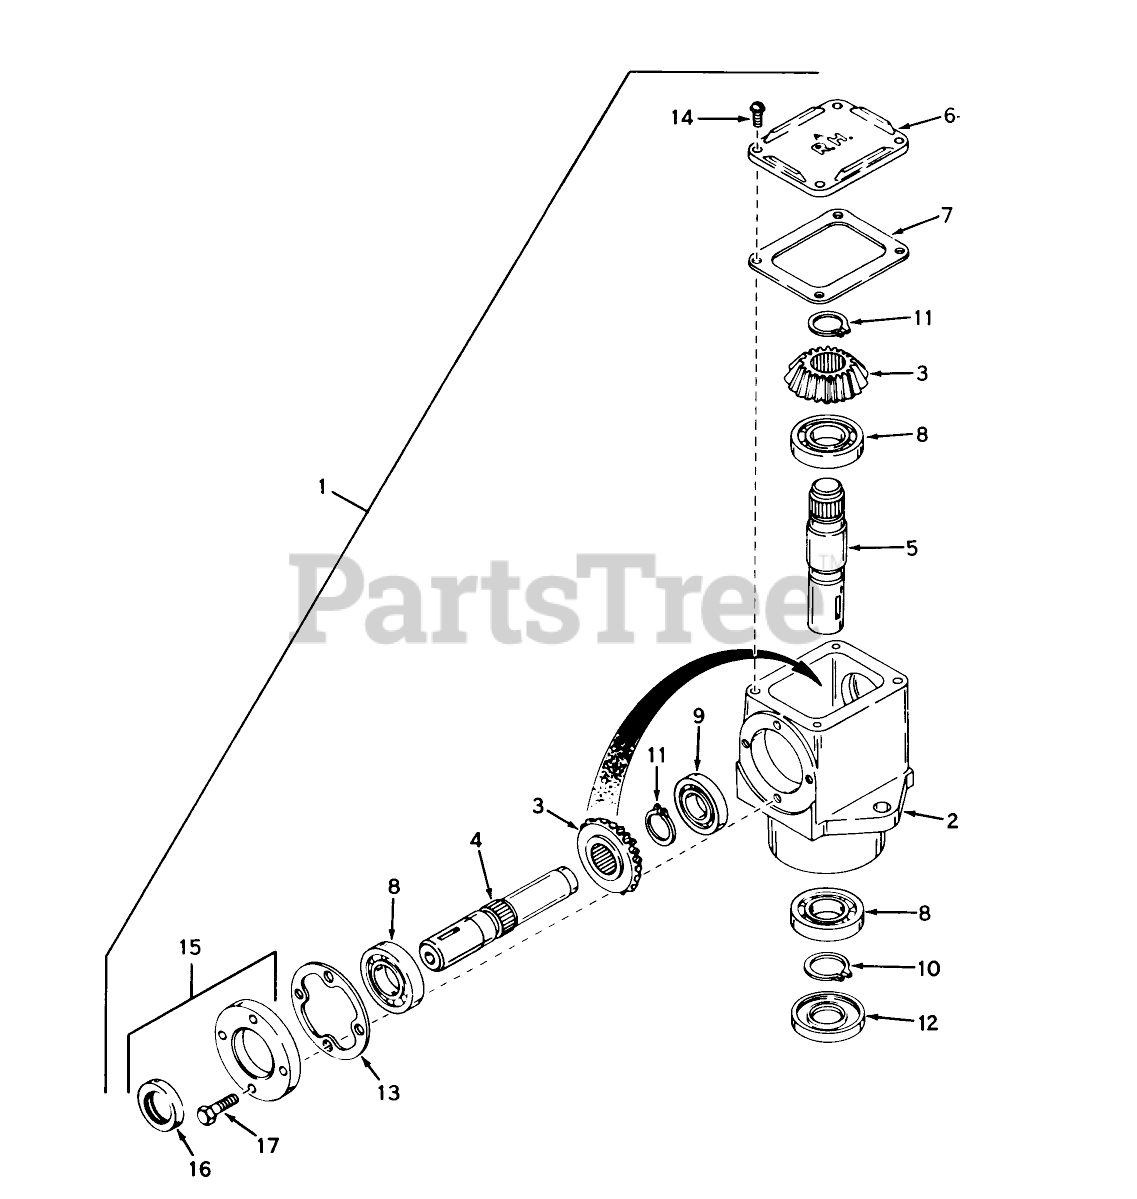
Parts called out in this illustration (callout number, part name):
1	Head Assy., Right Hand(Incl. Nos. 2 thru 15)
2	Housing, Right Angle Drive
3	Bevel Gear
4	Shaft, Input Pinion
5	Shaft, Output
6	Cover, Right Hand
7	Gasket
8	Bearing
9	Bearing
10	Ring-Snap
11	Ring-Snap
13	Gasket
14	Screw, Rd. Hd. Self Tap
15	Cap Seal Assy., Retainer (Incl. Nos. 16 17)
16	Oil Seal
17	SCREW-HH
